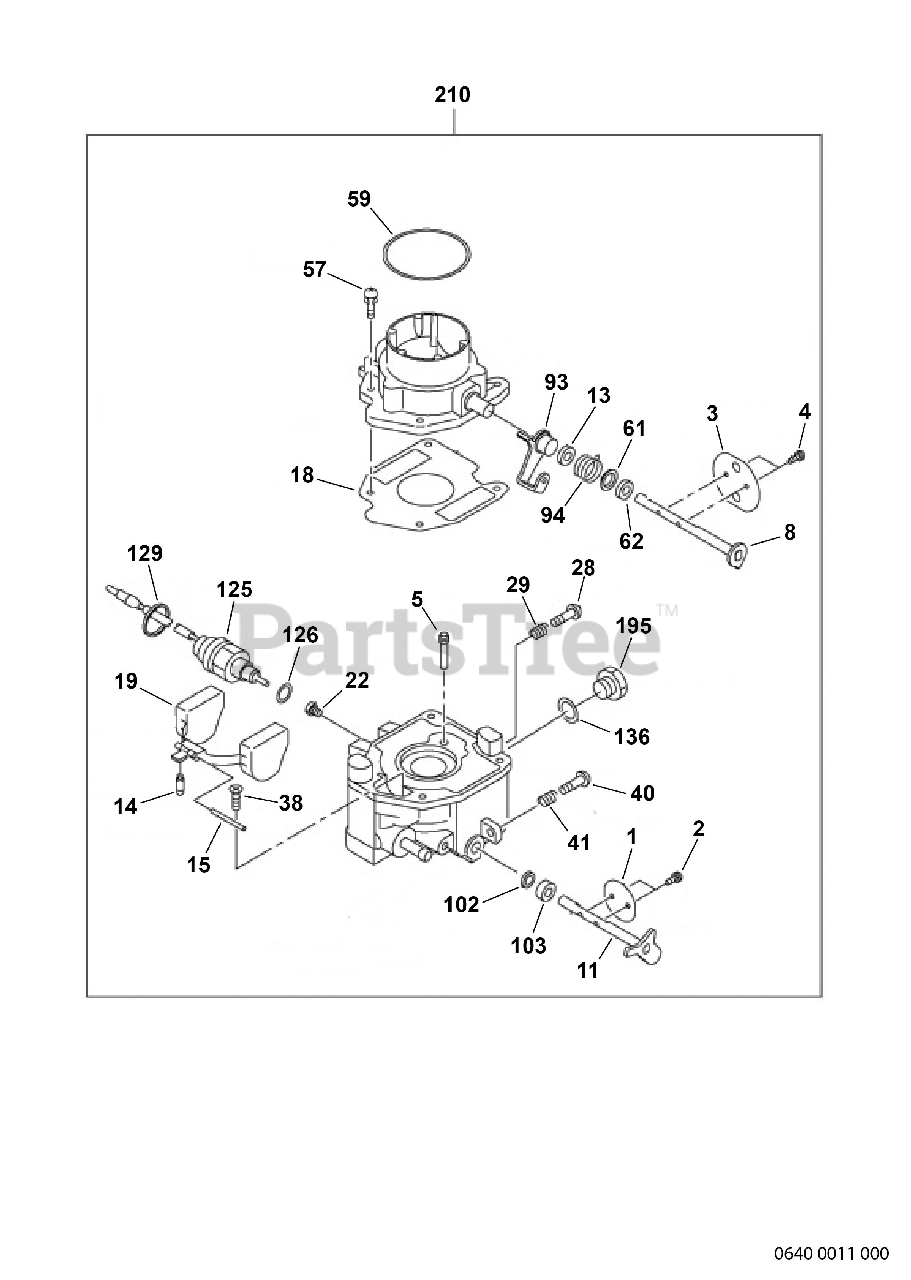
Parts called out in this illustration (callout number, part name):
1	VALVE,THROTTLE
2	SCREW,VALVE SET
4	SCREW SET(VALVE)
8	SHAFT ASSY,CHOKE
11	SHAFT ASSY,THROTTLE
13	RING(CHOKE LEVER)
18	GASKET,AIR HORN
38	SCREW SET(FLOAT PIN)
40	SCREW,THRO.ADJUST
41	SPRING(ADJUST SCREW)
57	SCREW SET(AIR HORN)
59	O-RING,AIR HORN
62	FILTER(CHOKE SHAFT)
93	LEVER ASSY,CHOKE
103	COLLAR(THRO.SHAFT)
125	VALVE CP,(SOLENOID)
126	GASKET,MAIN PASSAGE
129	CLAMP(SOLENOID)WIRE
